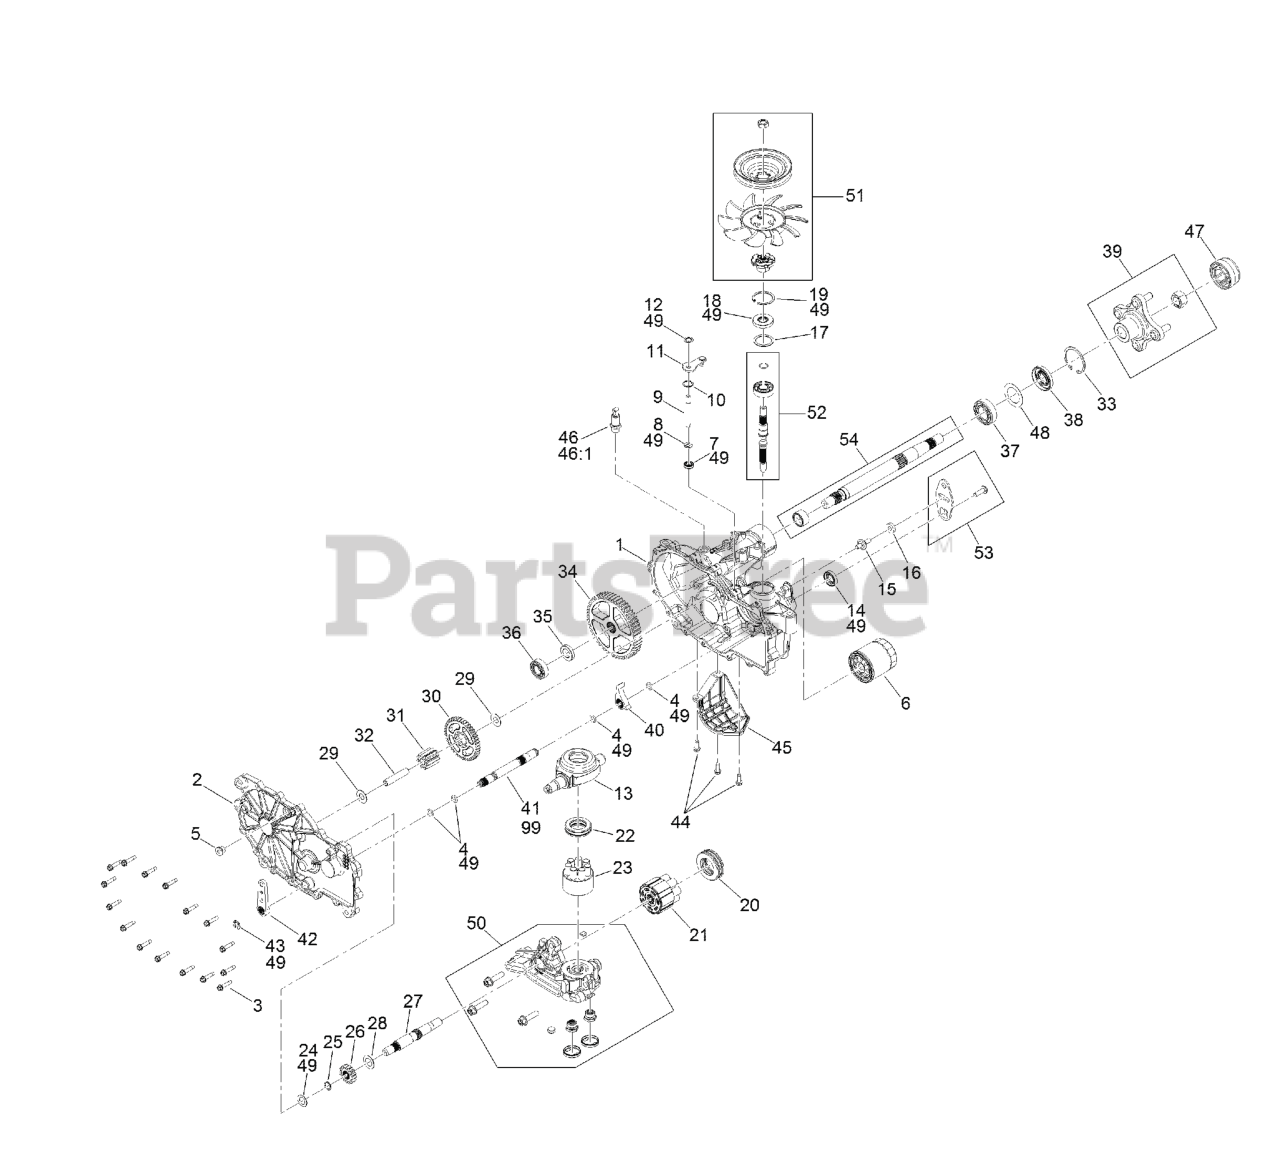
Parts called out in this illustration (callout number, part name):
1	MAIN HOUSING KIT
2	LH SIDE COVER KIT
3	SCREW-HHF
5	PLUG-THREAD, STRAIGHT
6	ELEMENT-OIL FILTER, HYD
7	SEAL-LIP
8	RING-RETAINING, EXTERNAL
9	ROD-BYPASS
10	RING-RETAINING, INTERNAL
11	ARM-BYPASS
12	RING-RETAINING, EXTERNAL
13	SWASHPLATE-TRUNNION
14	SEAL-LIP
16	PUCK-FRICTION
18	SEAL-LIP
19	RING-RETAINING
20	BEARING-THRUST
21	MOTOR CYLINDER BLOCK KIT
22	BEARING-THRUST
23	PUMP BLOCK ASM
24	WASHER-FLAT
25	RING-RETAINING
26	GEAR-16T
27	SHAFT-MOTOR
30	GEAR-43T
31	GEAR-11T
32	PIN-JACKSHAFT
33	RING-RETAINING
34	GEAR-54T
36	BEARING-BALL
37	BEARING-BALL
39	HUB KIT
40	PAWL-BRAKE
41	SHAFT-BRAKE, INBOARD
42	HANDLE-BRAKE
43	RING-RETAINING, EXT
45	GUARD-FILTER, LH
46	ADAPTER-STRAIGHT
46:1	O-RING
47	COVER-NUT, AXLE
49	SEAL KIT
50	CENTER SECTION KIT
51	FAN PULLEY KIT
52	INPUT SHAFT KIT
53	CONTROL ARM KIT
54	AXLE SHAFT KIT
99	BRAKE SHAFT SEAL KIT
